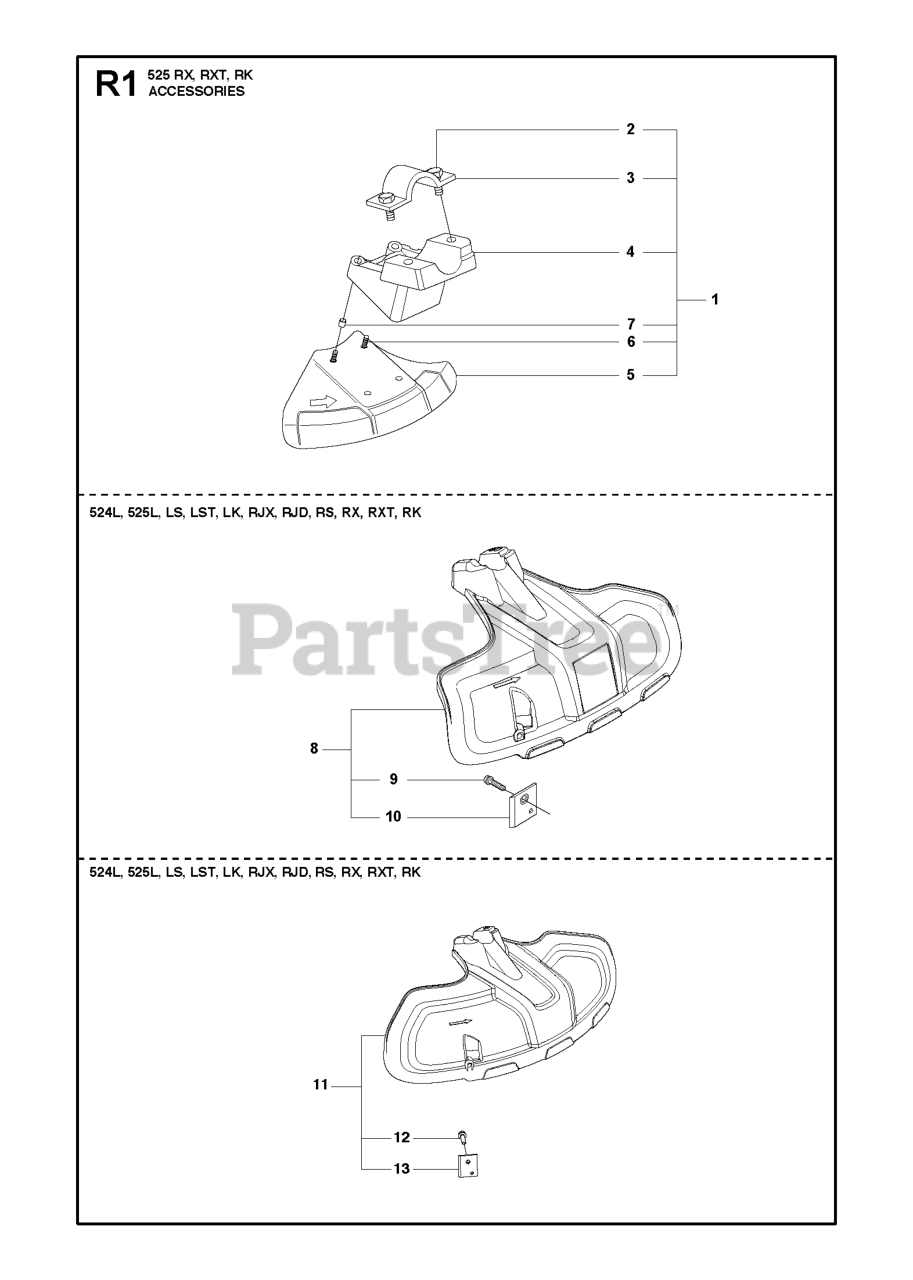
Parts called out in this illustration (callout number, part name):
1	TRIMMER GUARD ASSY
2	SCREW IHSCFMO
3	CLAMP
5	METAL GUARD 200MM
7	LOCKING NUT
8	TRIMMER GUARD 323L MFL.
9	SCREW ITXSCFT PW4.8X16 T27 CH
10	LINE CUTTER
11	COMBINATION GUARD
12	SCREW ITXSCFT PW4.8X16 T27 CH
13	LINE CUTTER
